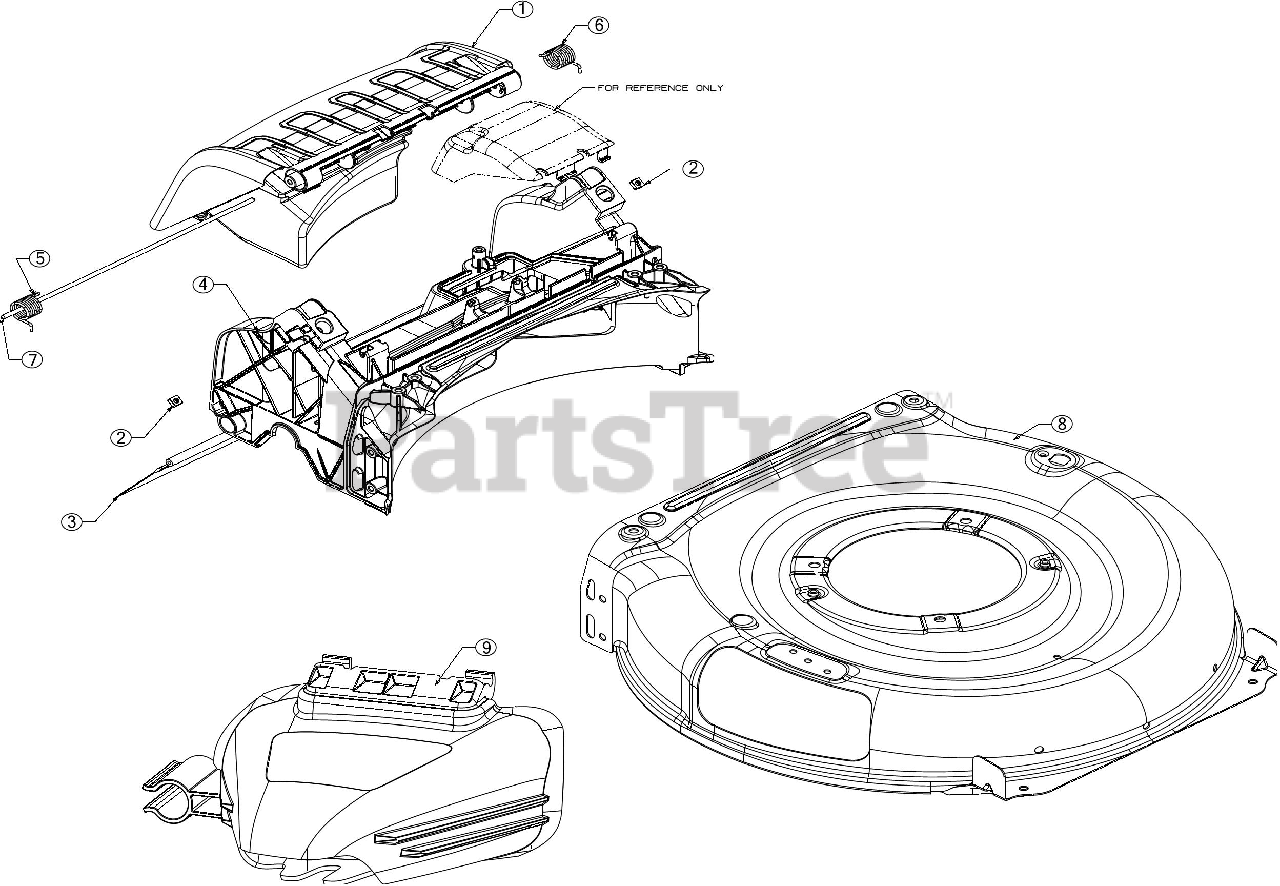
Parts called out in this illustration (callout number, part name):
2	SQUARE NUT 1/4-20
3	TRAILSHIELD
5	TORSION SPRING (RH)
6	TORSION SPRING (LH)
7	REAR DOOR PIVOT ROD
8	21" DECK ASSEMBLY
8	21" DECK (3N1)
9	MOWER BLOWER CHUTE
